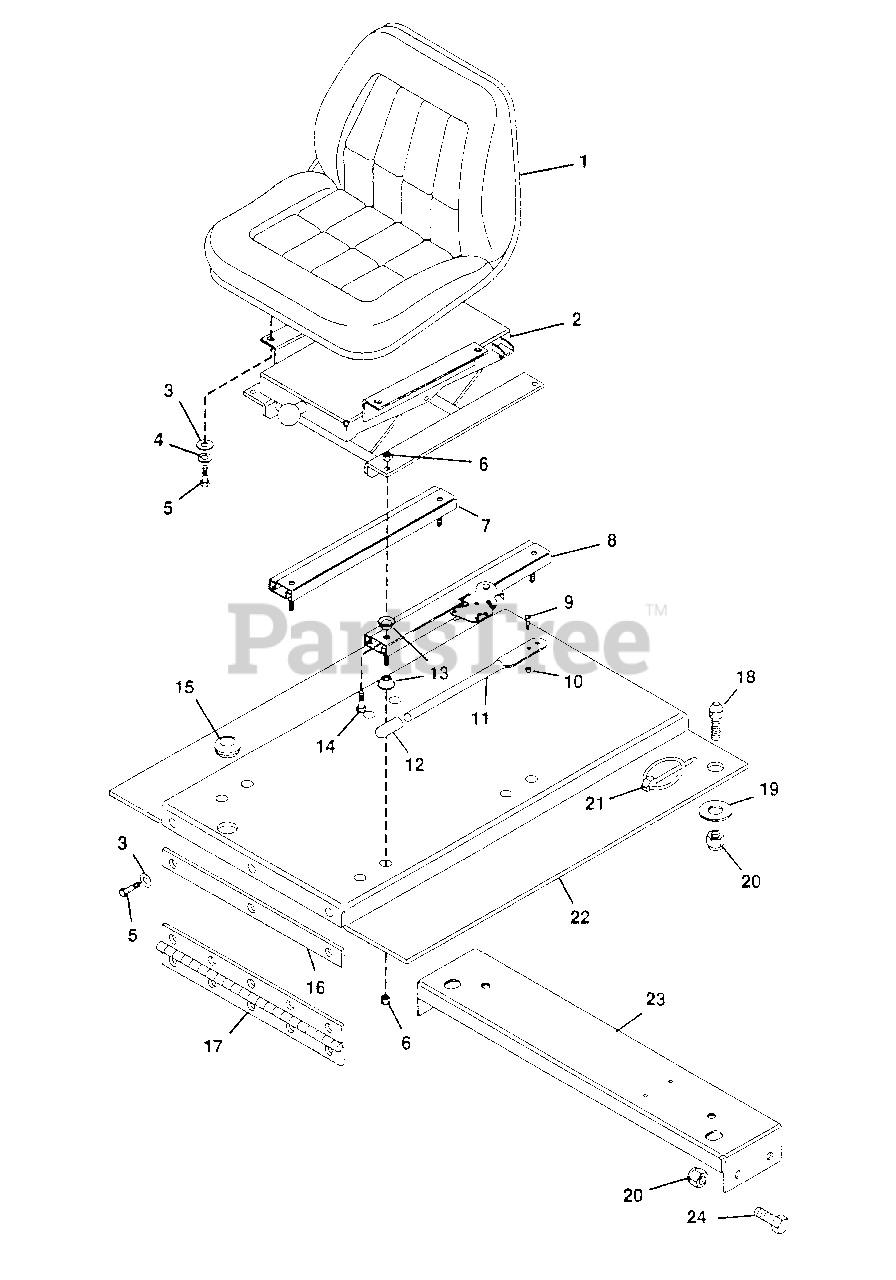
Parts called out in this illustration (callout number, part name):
1	Seat, ProMaster
2	Seat, Suspension
3	Washer, Flat .344x.688x.065
4	Washer, Lock 5/16 Reg.
5	Bolt, Hex 5/16-18x.75
6	Nut, Lock 5/16-18
7	Adjuster, Seat
8	Adjuster, Seat w/Latch
9	Screw, Machine 10-24x.625 PHD
10	Nut, Lock 10-24
11	Handle, Seat Slide
12	Tips, Brake Lock Lever
13	Bush., Flg. .375x1.16x.320 Stl.
14	Bolt, Hex 5/16-18x1.00
15	Grommet, .75
16	Plate, Clamping
17	Hinge
18	Pin, Catch
19	Washer, Flat .531x1.062x.095
20	Nut, Lock 1/2-13
21	Pin, Klik
22	Plate, Deck
23	Bracket, Deck Plate
24	Bolt, Hex 1/2-13x1.00
